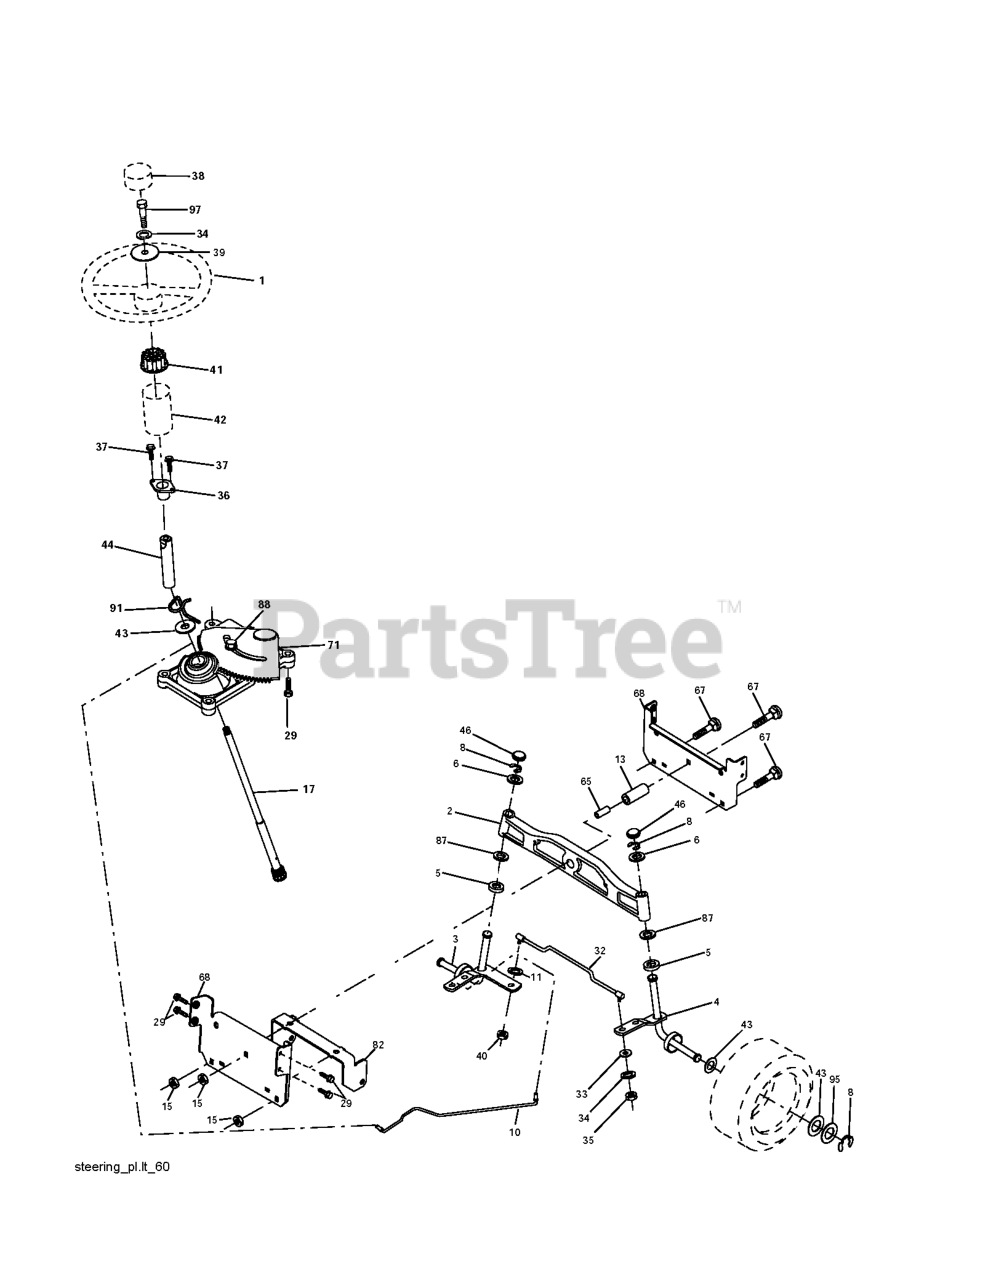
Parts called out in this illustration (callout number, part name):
1	STEERING WHEEL
2	AXLE ASSY FRONT
3	SPINDLE.ASM.LH.15"TIRES
4	SPINDLE.ASM.RH.15"TIRES
5	THRUST WASHER
10	DRAGLINK.15".TIRES.2001
11	WASHER, LOCK 3/8
13	TUBE, PIVOT AXLE
15	NUT
17	SHAFT STEERING SPLINE
29	SCREW, 3/8-16X3/4
33	WASHER M
34	WASHER.LOCK.HVY.HLCL.SPR.5/16
35	NUT, CROWNLOCK
36	BUSHING, STEERING
37	SCREW.TT.#10-32X.5.3/8.FLANGE
38	INSERT.CAP.STRG.WH.GRAY
39	WASHER.11/32
41	ADAPTER, WHEEL STNG..
42	BOOT STEERING
44	SHAFT.EXTEN.STRG.SPLINE
46	CAP.SPINDLE.BLACK
65	SPACER BRACE AXLE
67	BOLT CARRIAGE
68	BRACE.AXLE.15"TIRES
71	STEERING ASM
82	BRACKET.SUSP.CHASSIS.FRONT.15
87	WASHER, FLAT .781 X 1 1/2"
88	BOLT, SHOULDER 7/16-20
91	CLIP.STEERING
95	WASHER.HARDENED
